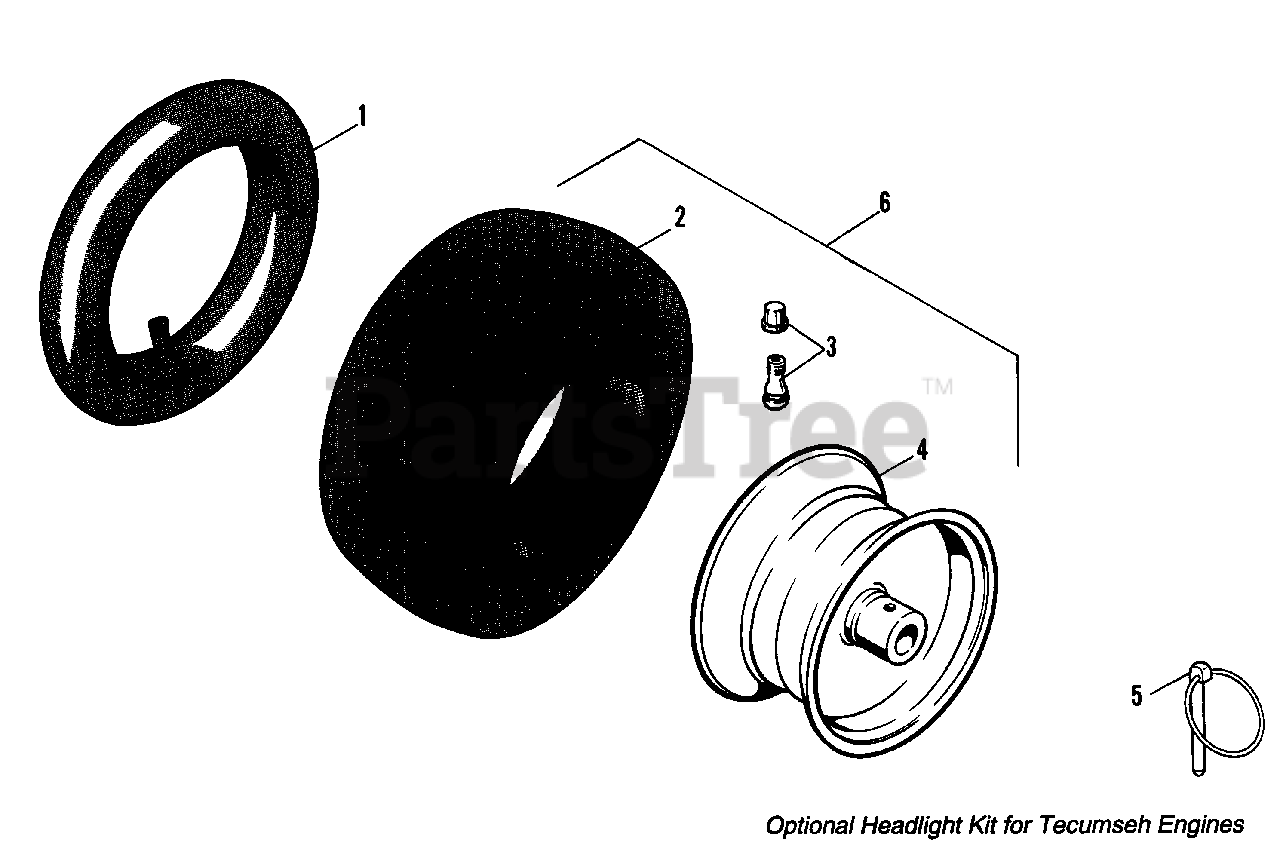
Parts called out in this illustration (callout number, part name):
1	TUBE (Service Only) 4.80/4.00-8
2	TIRE, (Snow Hog)
3	VALVE STEM & CAP
4	WHEEL ASSY.
6	WHEEL & TIRE ASSY. (Incl. Ref. Nos. 2, 3 & 4)
